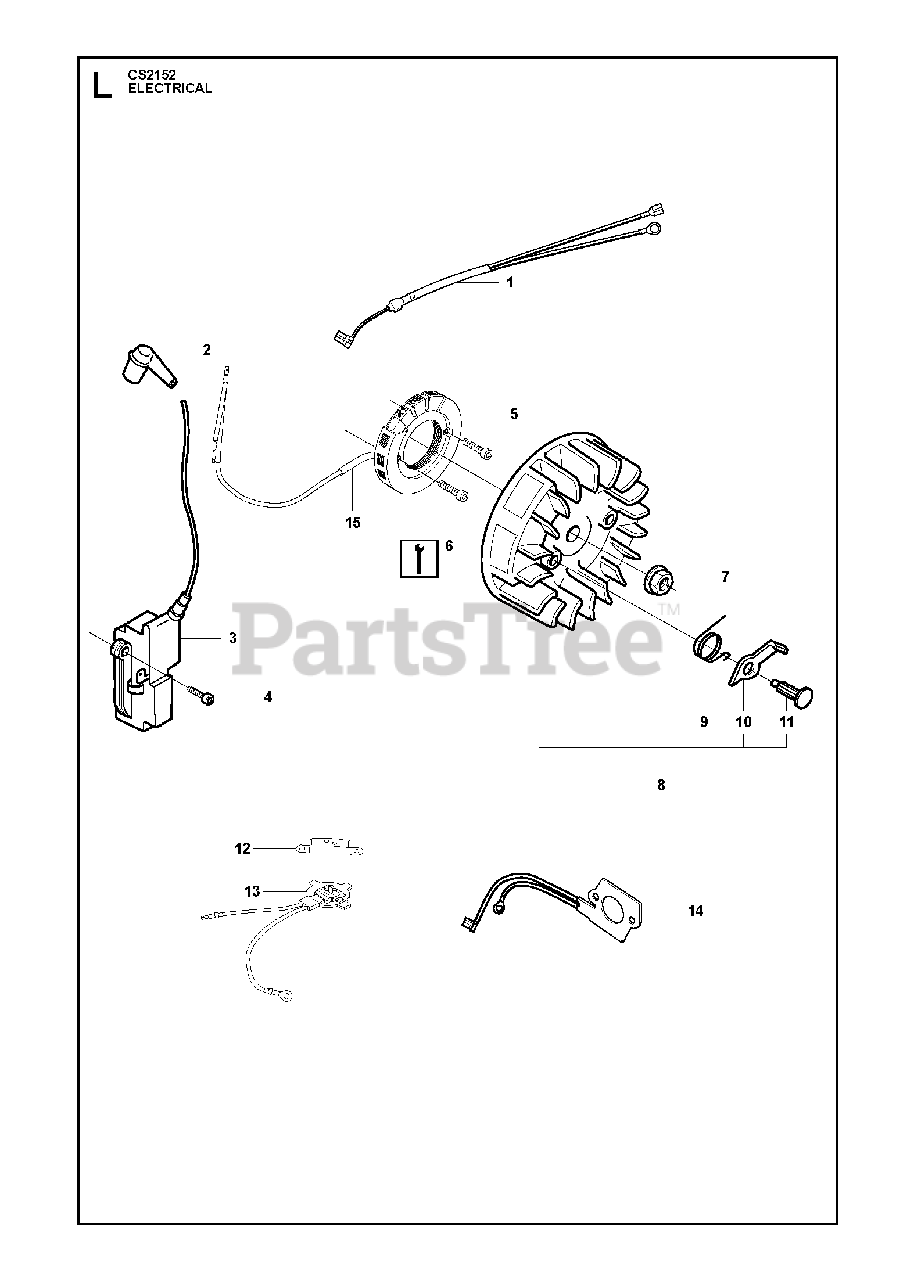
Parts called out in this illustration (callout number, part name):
1	WIRING ASSY
1	WIRING ASSEMBLY
2	SPARK PLUG CONN. KIT
3	IGNITION MODULE
5	GENERATOR
5	GENERATOR STATOR
7	NUT W/ WASHER
8	FLYWHEEL
8	FLYWHEEL (G)
9	%SPRING, STARTER CATCH
10	PAWL
11	RIVET
12	RETAINER
13	THERMOSTAT ASSY
14	HEATING PLATE
15	CABLE COVER
